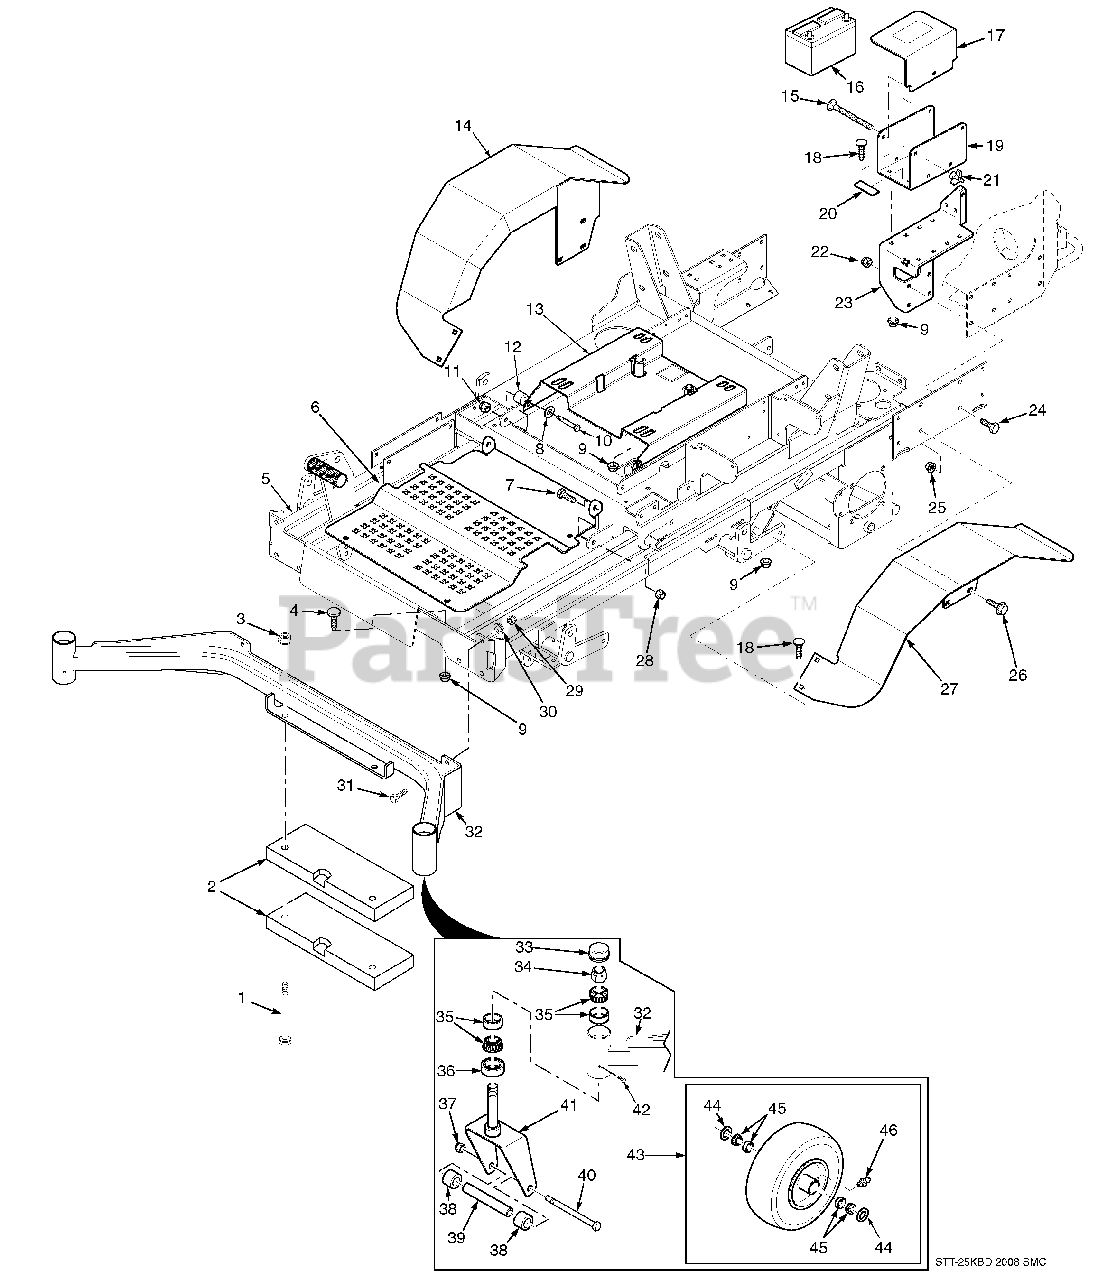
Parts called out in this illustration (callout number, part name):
1	Bolt, Hex Head 1/2-13 x 3.5"
2	Weight
3	Nut, Hex Elastic Stop 1/2-13
4	Bumper, Rubber 5/16-18 x 5/8"
5	Main Frame Assembly w/Decals
6	Foot Plate
7	Bolt, Hex Head 3/8-16 x 1"
8	Flatwasher, 3/8-.391 x .938 x .105
9	Nut, Hex Serrated Flange 5/16-18
10	Bolt, Hex Head 3/8-16 x 2.0"
11	Nut, Elastic Stop 3/8-16
12	Spacer Bushing
13	Seat Plate Weldment w/Decal
14	Fender Weldment, RH
15	Bolt, Carriage 1/4-20 x 6"
16	Battery
17	Cover, Battery
18	Bolt, Carriage 5/16-18 x 3/4"
19	Plate, Battery Box
20	Rubber Pad
21	Wing Nut, 1/4-20 x 3/4"
22	Nut, Elastic Stop 3/8-16
23	Battery Box Mount
24	Bolt, Hex Head 3/8-16 x 1"
25	Nut, Hex Serrated Flange 3/8-16
26	Screw, Hex Serrated Flange 3/8-16 x 1"
27	Fender Weldment, LH
28	Nut, Hex Elastic Stop 3/8-16
29	Nut, Elastic Stop 7/16-14
30	Lockwasher, 7/16"
31	Bolt, Hex Head 7/16-14 x 1-1/4"
32	Extention Weldment, Caster
33	Cap, Grease
34	Nut, Hex Elastic Stop 1.0"-14
35	Bearing W/Race
36	Seal, 2.00" OD. x 1.625" Bore
37	Nut, Hex Elastic Stop 1/2-13
38	Spacer, Caster Wheel
39	Sleeve, Caster Wheel (61V)
40	Bolt, Hex Head 1/2-13 x 9-1/2" (61V)
41	Yoke Weldment, Caster (61V )
42	Plug, 1/4-28 THD Form
43	Wheel Assembly,
45	Bearing w/ Race
46	Grease Fitting
